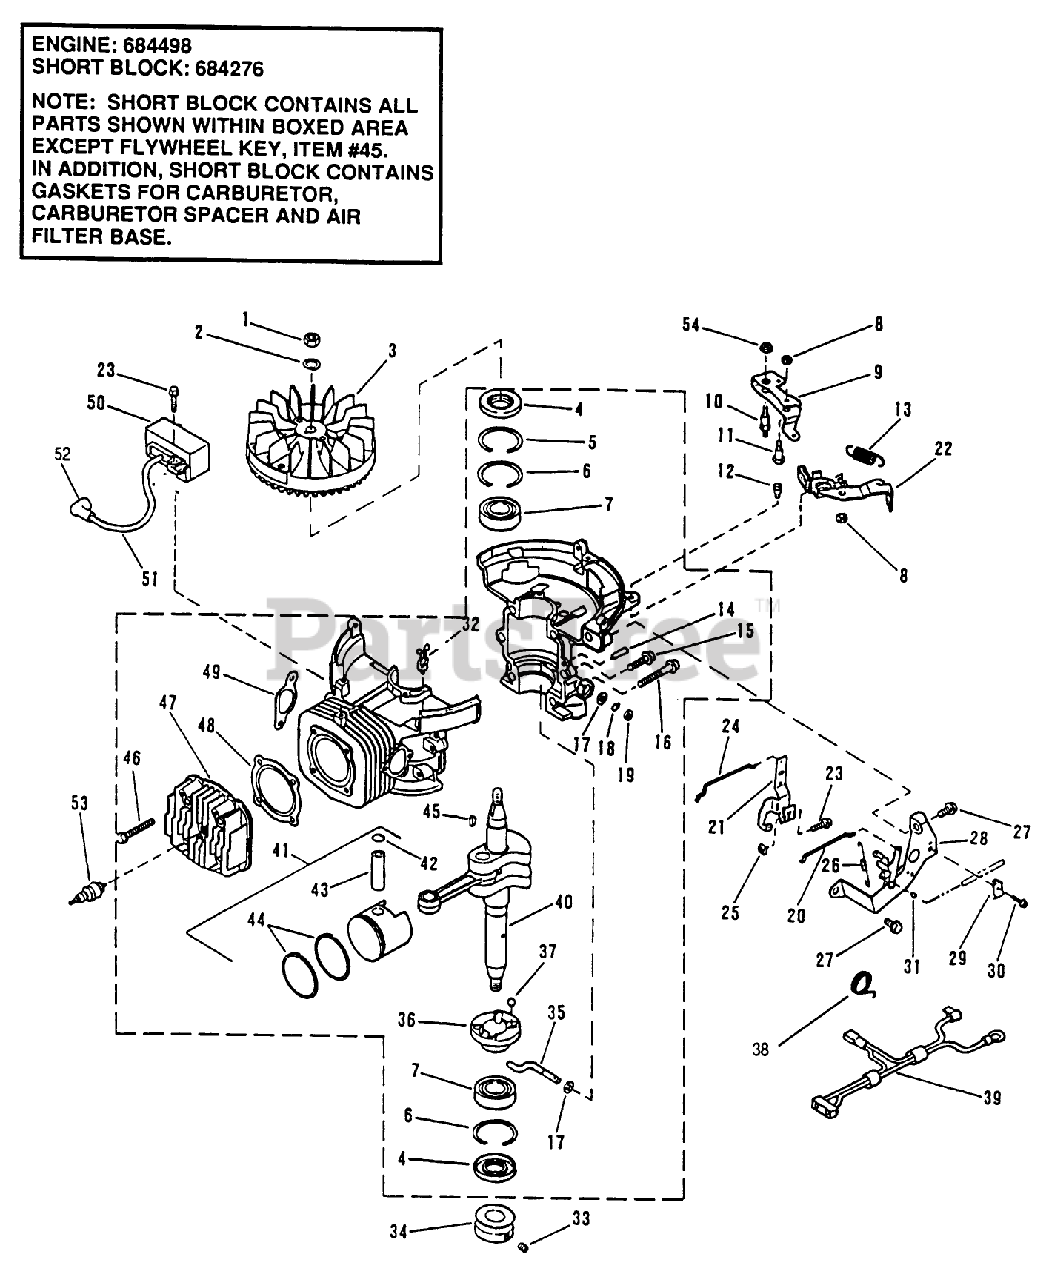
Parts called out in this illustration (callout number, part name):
4	SEAL - OIL SM
5	RING-RETAINER SM
7	BEARING-BALL SM
8	LOCKNUT E
9	ACT.BRAKE LVR. SM
10	STUD-SHOULDER SM
13	SPRING-BRAKE
15	SCREW-H.W.HD. F
16	SCREW-HEX W.H. SM
18	RING-RETAINING
19	SEAL - OIL SM
24	ROD-THROTTLE SM
26	SPRING-GOV. SM
28	GOVNR BRKT SM
32	WIRE TIE SM
34	PULLEY - ENGINE S
44	RING SET S
47	CYLINDER HEAD SM
49	GASKET - EXH SM
51	HI-TENS.LEAD
52	COVER & TERM. AY S
53	SPARK PLUG
